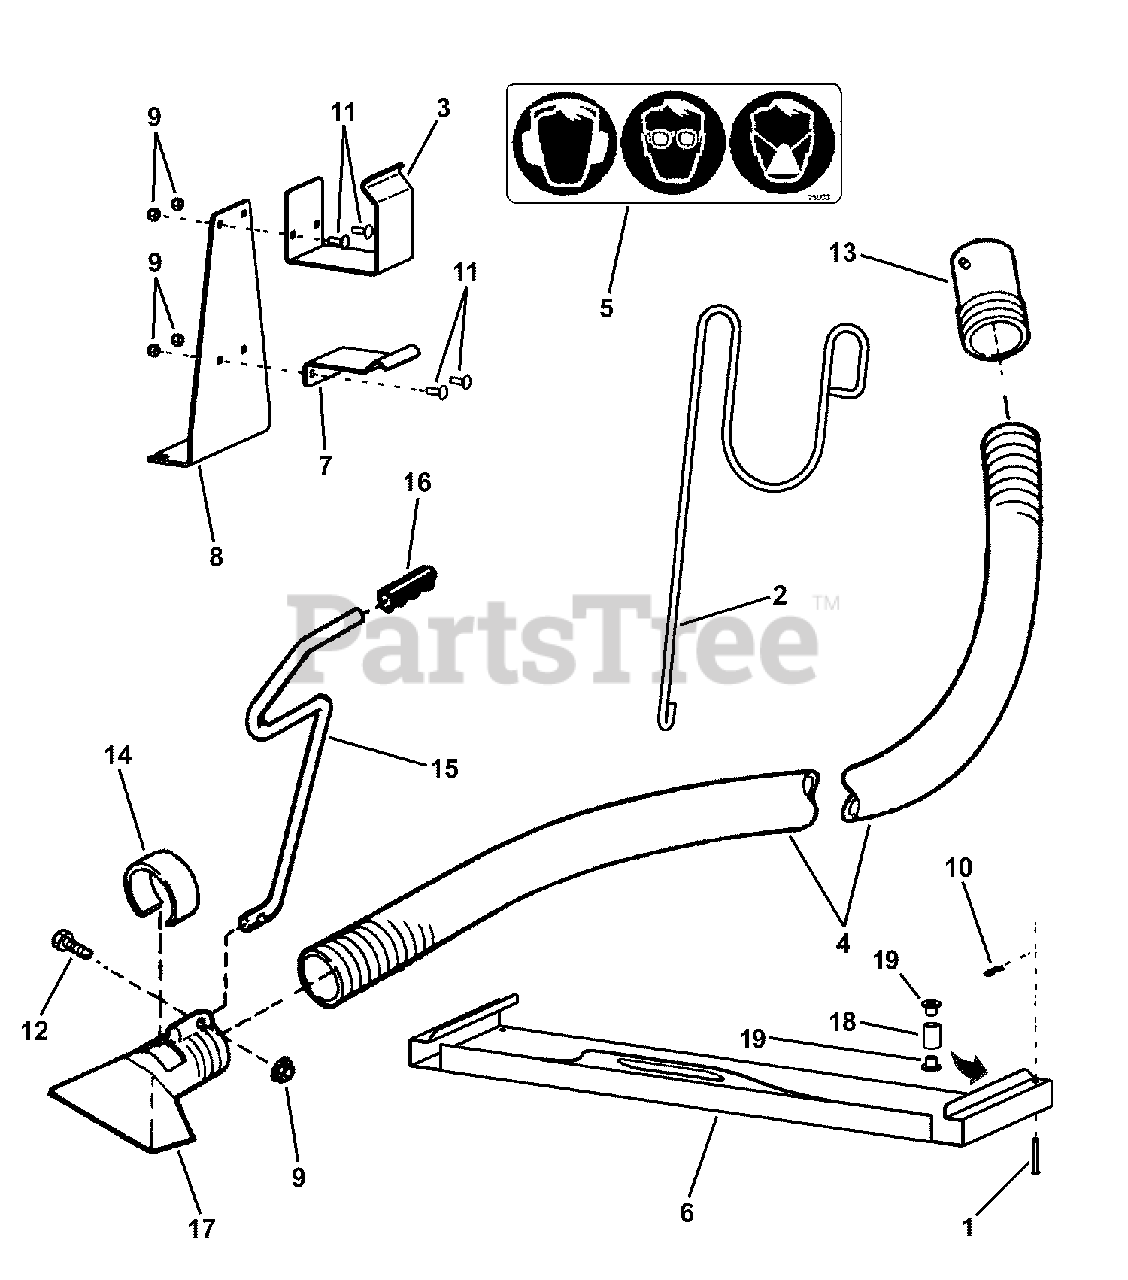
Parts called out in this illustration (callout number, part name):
1	PIN, 1/4 x 1-1/8" Clevis (Current versions)
1	PIN, 3/16 x 1-1/2" Clevis (Early versions)
2	ROD, Hose/Handle Holder
3	BRACKET, Upper Hose Clamp
4	HOSE, 8 inch Diameter x 8 feet Long
5	DECAL, Personal Protection
6	BRACKET, Inlet Shutoff
7	BRACKET, Lower Hose Clamp
8	BRACKET, Hose Clamp Support
9	NUT, 1/4-20 Hex Nyloc
10	HAIR PIN, #13
11	CARRIAGE BOLT, 1/4-20 x 3/4, GR5
12	CAPSCREW, 1/4-20 x 1-1/4 Hex Head
13	COUPLER, Hose (Plastic)
14	RING, Shut Off (Plastic)
15	HANDLE
16	GRIP, Handle (Black Vinyl)
17	NOZZLE, Vacuum (Plastic)
18	SPACER
19	BUSHING, Flange
